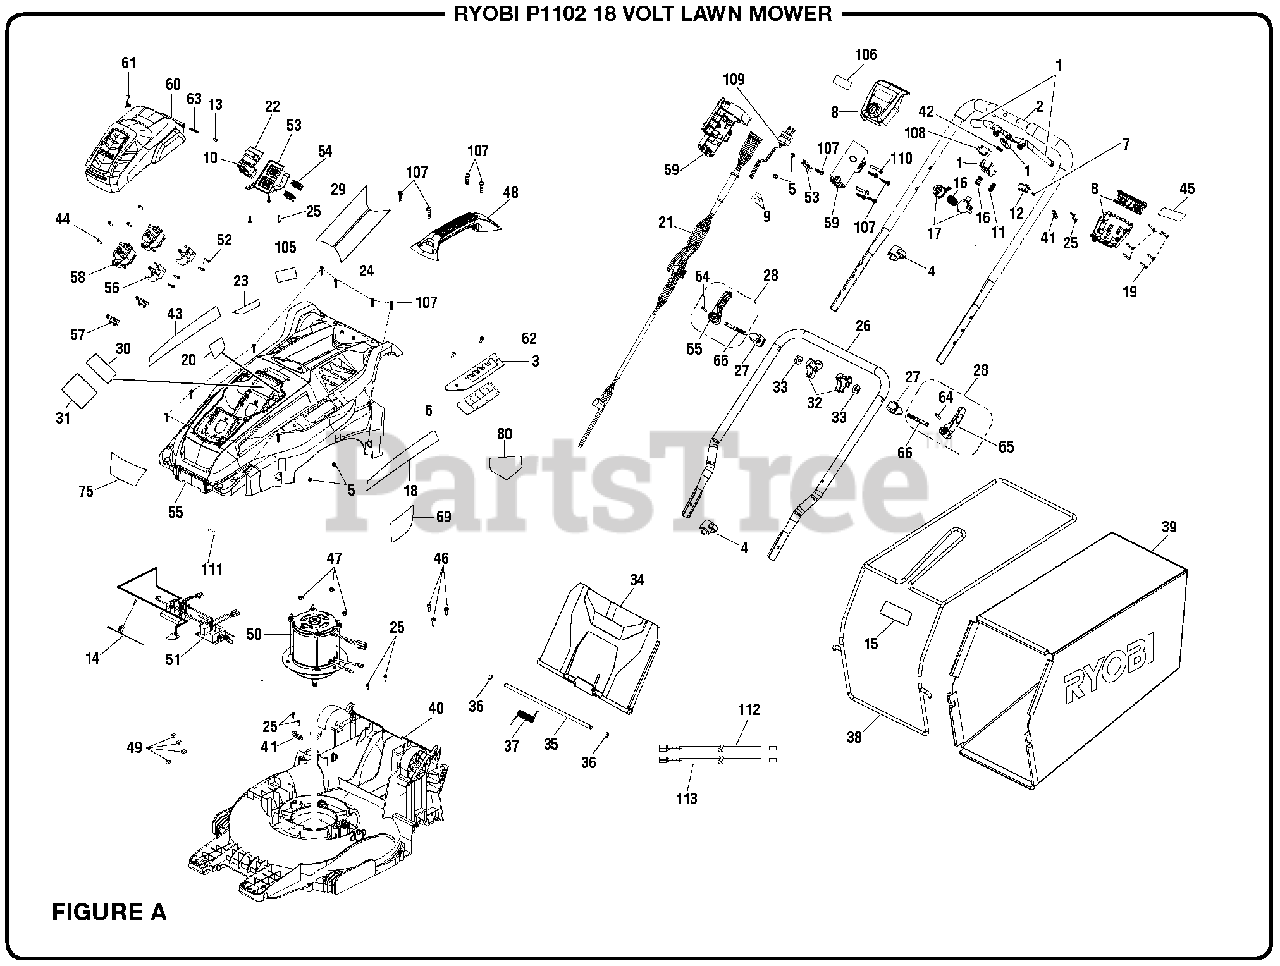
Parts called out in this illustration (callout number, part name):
1	Trigger Handle Assembly
2	Upper Handle Assembly
3	Height Adjustment Plate
4	Cord Clamp
5	Lock Nut (M5)
6	Dust Gasket
7	Screw (M4 x 10 mm, T20 Torx Pan Hd.)
8	Trigger Housing Assembly
9	Wire Connector (Closed End)
10	Start Key
11	Compression Spring
13	Battery Door Axle
14	Lead Wire w/Terminal Block
15	Bag Door Label
16	Button Return Spring
17	Start Button Assembly
18	Lithium Label (Left)
19	Screw (M4 x 30 mm, T15 Torx Pan Hd.)
20	Fuel Gauge Label
21	Starter Cable (Long)
22	Slide Door
23	Icon Warning Label
24	Warning Icon Label (Right)
25	Screw (M4 x 16 mm, T20 Torx Pan Hd.)
26	Lower Handle
27	Pressure Block
28	Handle Lock Assembly
29	Warning Icon Label (Left)
30	Start Key Label (Eng)
31	Start Key Label (FR/SP)
33	Block Washer
34	Rear Discharge Door
35	Rear Door Axle
36	Retaining Ring (E)
37	Torsion Spring (Rear Door)
38	Bag Frame
39	Bag
41	Cord Clip
43	Lithium Label (Right)
44	Screw (M4 x 16 mm)
45	Starting Instructions Label
46	Screw (M3 x 8 mm, Pan Hd.)
47	Lock Nut (M6)
49	Rubber Block
51	Start Circuit Board
52	Screw (M4 x 16 mm, T20 Torx Socket Pan Hd.)
53	Key Holder Assembly
54	Key Receptacle
55	Deck Cover
56	Press Cover (Battery Connect)
57	Plate (Battery Connect)
58	Base (Battery Connect)
59	AC Plug Housing Assembly
60	Battery Cover
61	Torsion Spring (Battery Door)
62	Screw (M5 x 16 mm, Pan Hd.)
63	Pressure Spring
64	Spring Pin
66	Quick Lock Press
69	Height Adjust Label
75	Ryobi Logo Label (Front)
80	Cut Finger Label
105	Data Label
106	Ryobi Logo Label (Handle)
107	Screw (M4 x 20 mm)
108	Micro Switch
109	Plug Wire
110	Screw (M5 x 30 mm)
111	Wire Connector (Closed End)
112	Lead Wire (Red)
113	Lead Wire (Brown)
